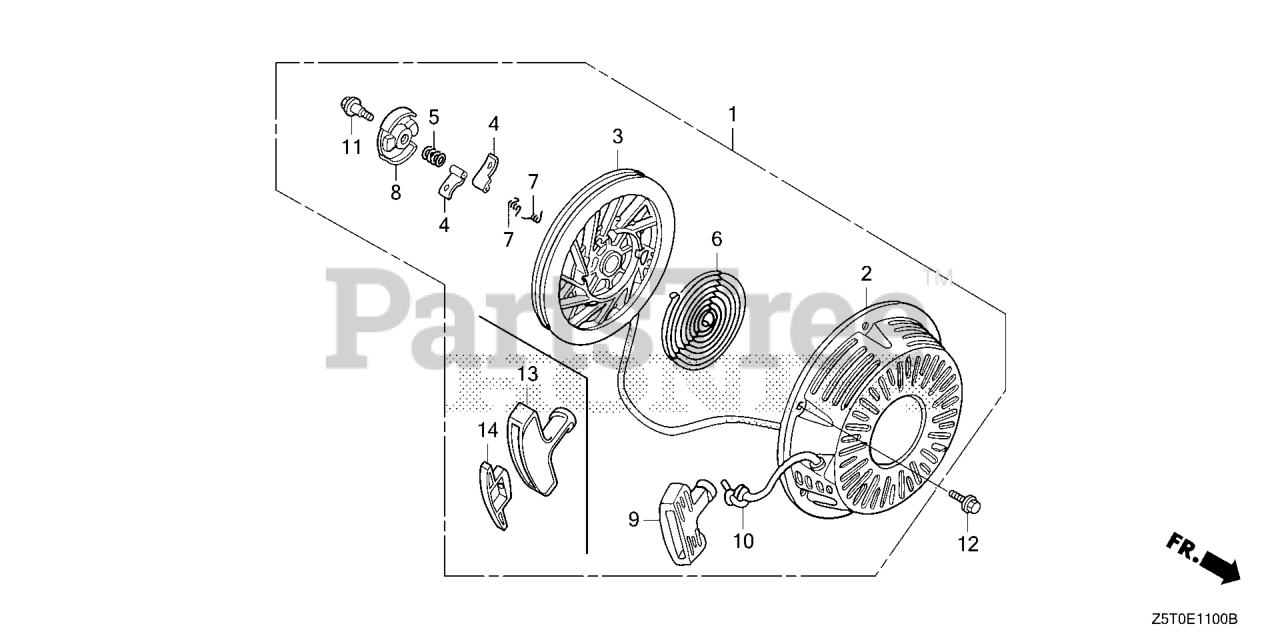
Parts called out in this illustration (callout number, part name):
1	STARTER ASSY., RECOIL *NH1* (FOR U.S.A.) (BLACK)
2	CASE, RECOIL STARTER *NH1* (BLACK)
3	PULLEY, RECOIL STARTER
4	RATCHET, STARTER
5	SPRING, FRICTION
6	SPRING, STARTER RETURN
7	SPRING, RATCHET
8	RETAINER, SPRING
10	ROPE, RECOIL STARTER (#6X64") (N/A: USE P/N 08560-ZG921-11)
11	SCREW, CENTER
12	BOLT, FLANGE (6X10)
13	GRIP, STARTER
14	GRIP, REINFORCEMENT
